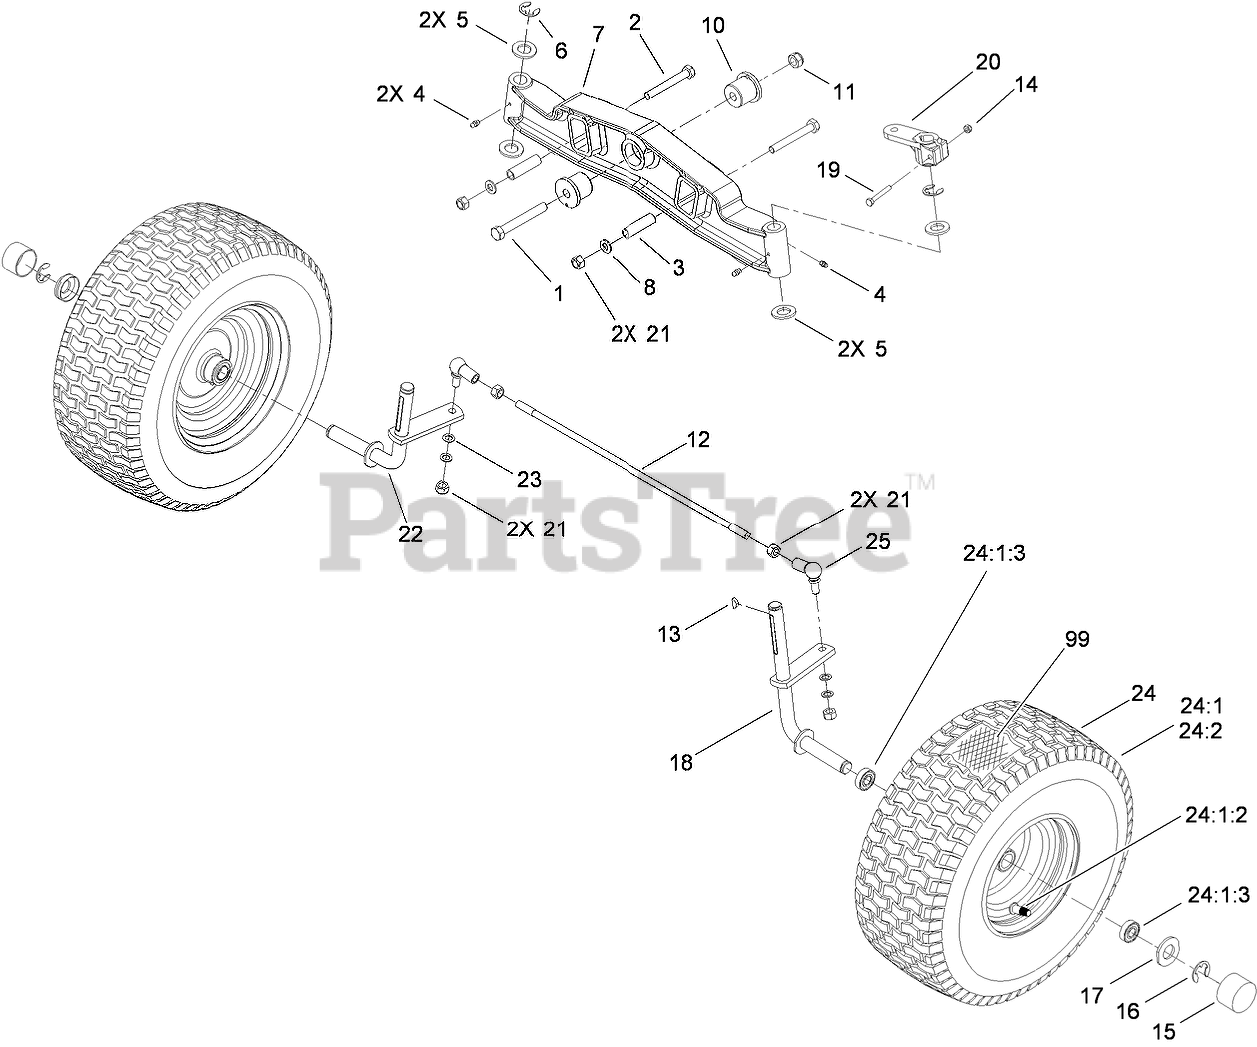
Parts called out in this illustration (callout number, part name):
1	SCREW-HH
2	SCREW-HH
3	SPACER
4	FITTING-GREASE
5	WASHER-FLAT
6	CLIP-SPRING
7	AXLE-FRONT
8	WASHER-FLAT
10	BUSHING-AXLE, FRONT
11	NUT-LOCKING, SELF
12	ROD-TIE, FRONT AXLE
13	KEY-WOODRUFF
14	NUT-LOCK
15	CAP-HUB
16	CLIP-SPRING
17	RETAINER-CAP, HUB
18	SPINDLE-LH
19	SCREW-HH
20	LEVER-SPINDLE, STEERING
21	NUT-LOCK, NI
22	RH SPINDLE ASM
23	Washer
24	WHEEL AND TIRE ASM
24:1	WHEEL ASM
24:1:2	Valve-Tire
24:1:3	BEARING-WHEEL
25	JOINT-BALL, ANGLE
99	TUBE-INNER
